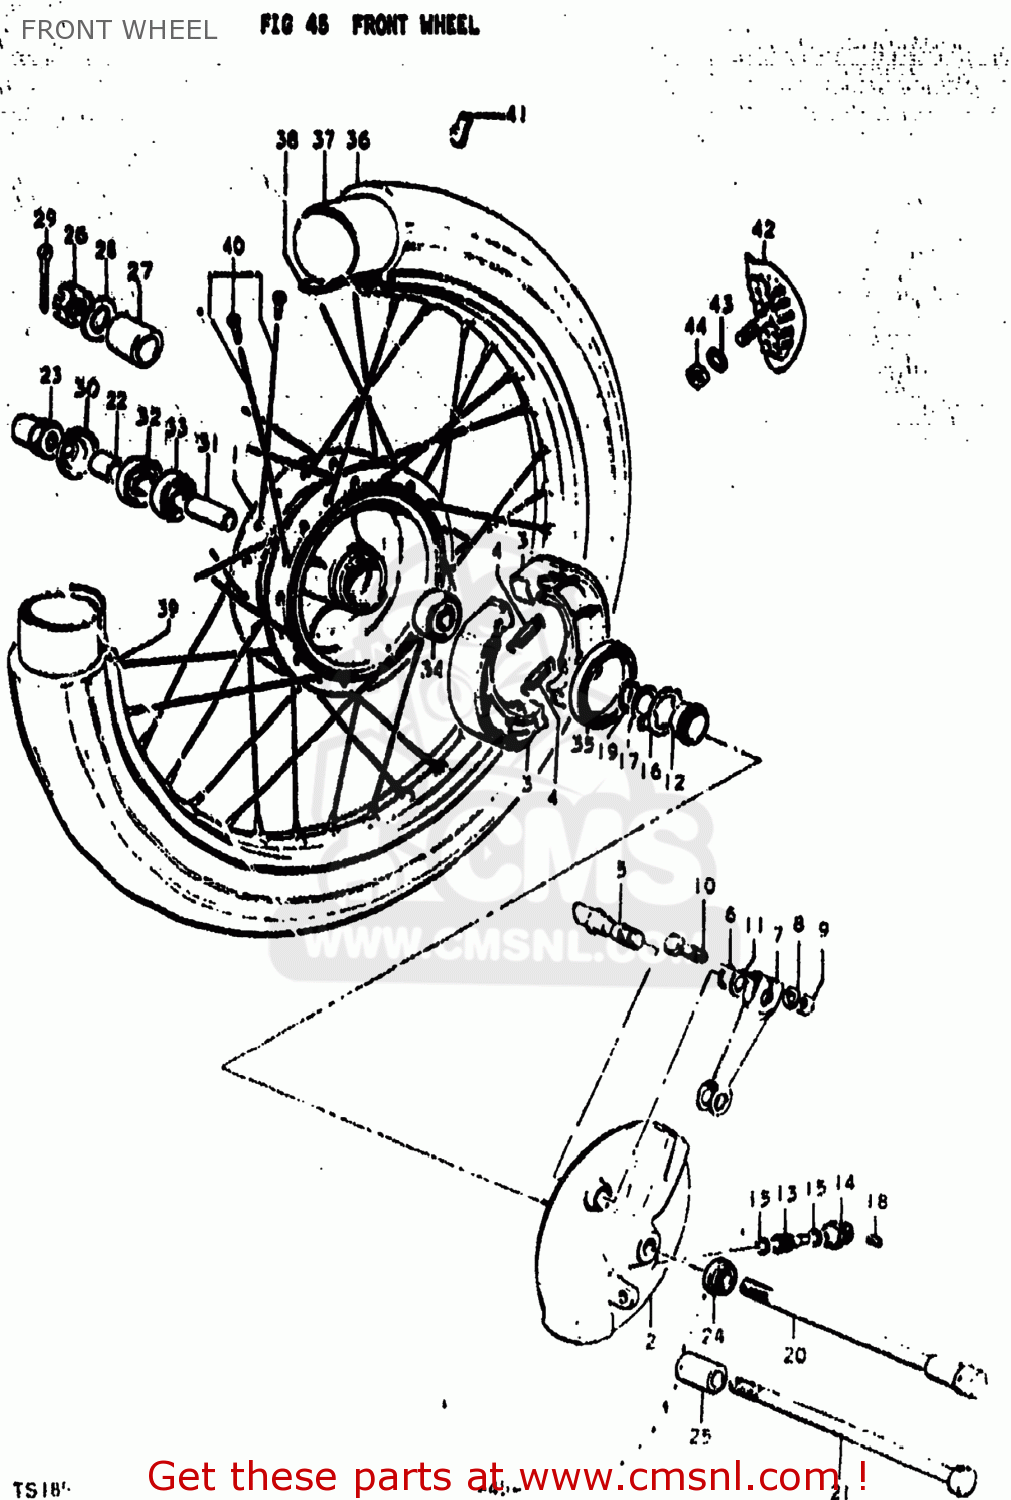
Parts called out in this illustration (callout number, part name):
1	HUB,FRONT
2	PANEL,FRONT HUB
3	SHOE,BRAKE
4	SPRING(L:34)
5	CAM,FRONT BRAKE
6	O RING(D:2.5,ID:11.4)
7	LEVER,FRONT BRAKE CAM
8	WASHER
9	NUT
10	BOLT
11	WASHER(12.5X20X1)
12	GEAR,SPEEDOMETER
13	PINION,SPEEDOMETER
14	BUSH,METER GEAR OUTER
15	WASHER (5.1X9X0.4)
16	DRIVER,SPEEDOMETER GEAR
17	WASHER(18.5X24X1)
18	SCREW
19	CIRCLIP
20	AXLE,FRONT
21	AXLE,FRONT
22	SPACER(12X18X16.4)
24	SPACER,FRONT AXLE,LEFT
25	SPACER (12X20X41)
26	NUT 12MM
27	SPACER (12X20X44)
28	WASHER
29	COTTER PIN
30	DUST SEAL,FRONT HUB DRUM
31	SPACER (12.6X19X52)
32	OIL SEAL
33	BEARING
34	BEARING, LH
35	SEAL,OIL(48X62X7)
36	TIRE,FRONT
37	TUBE
38	PROTECTOR,WHEEL,INNER
39	RIM,FRONT WHEEL
40	SPOKE SET,FRONT
41	BALANCER,WHEEL (50G)
42	STOPPER,BEAD
43	WASHER
44	NUT
